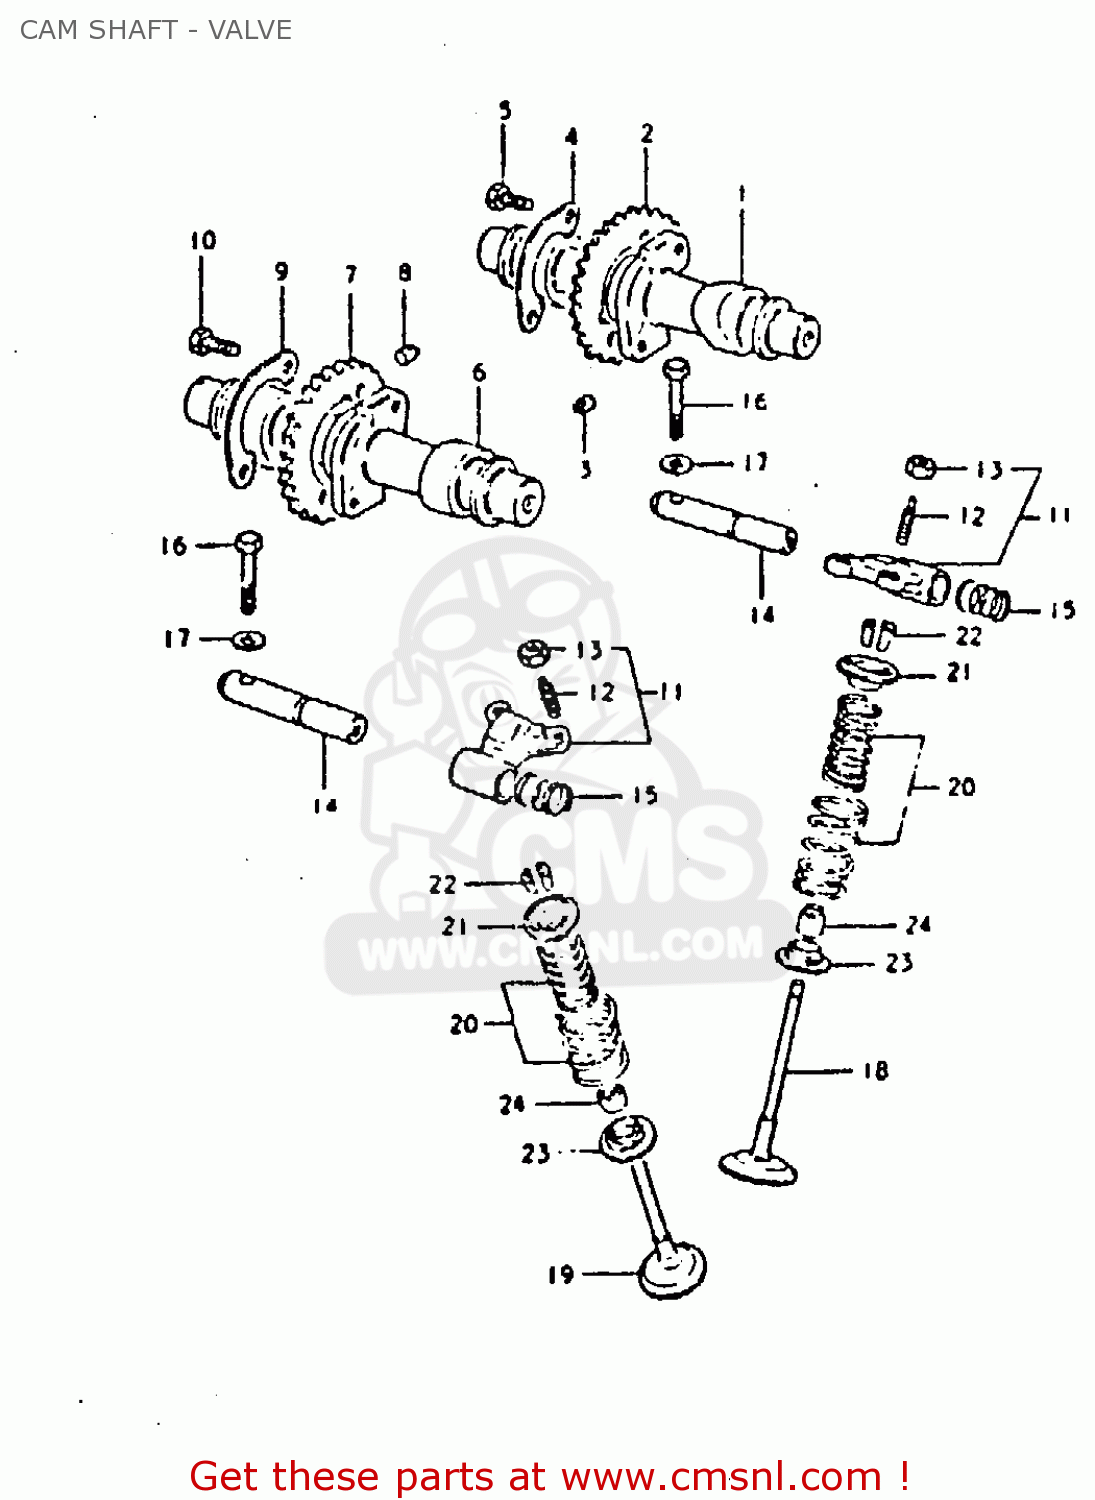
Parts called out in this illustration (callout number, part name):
1	CAMSHAFT,INTAKE
2	SPROCKET,INTAKE CAMSHAFT
3	PIN,SPROCKET
4	WASHER,CAM CHAIN SPROCKET
5	BOLT(6X12.5)
6	CAMSHAFT,EXHAUST
7	SPROCKET,EXHAUST CAMSHAFT
8	PIN,SPROCKET
9	WASHER,CAM CHAIN SPROCKET
10	BOLT(6X12.5)
11	ARM,VALVE ROCKER
12	SCREW
13	NUT,ADJUSTING
14	SHAFT,VALVE ROCKER ARM
15	SPRING
16	BOLT
17	WASHER
18	VALVE,INTAKE
19	VALVE,EXHAUST
20	SHIM,TAPPET
21	RETAINER,VALVE SPRING
22	COTTER VALVE
23	SEAT,VALVE SPRING
24	OIL SEAL
